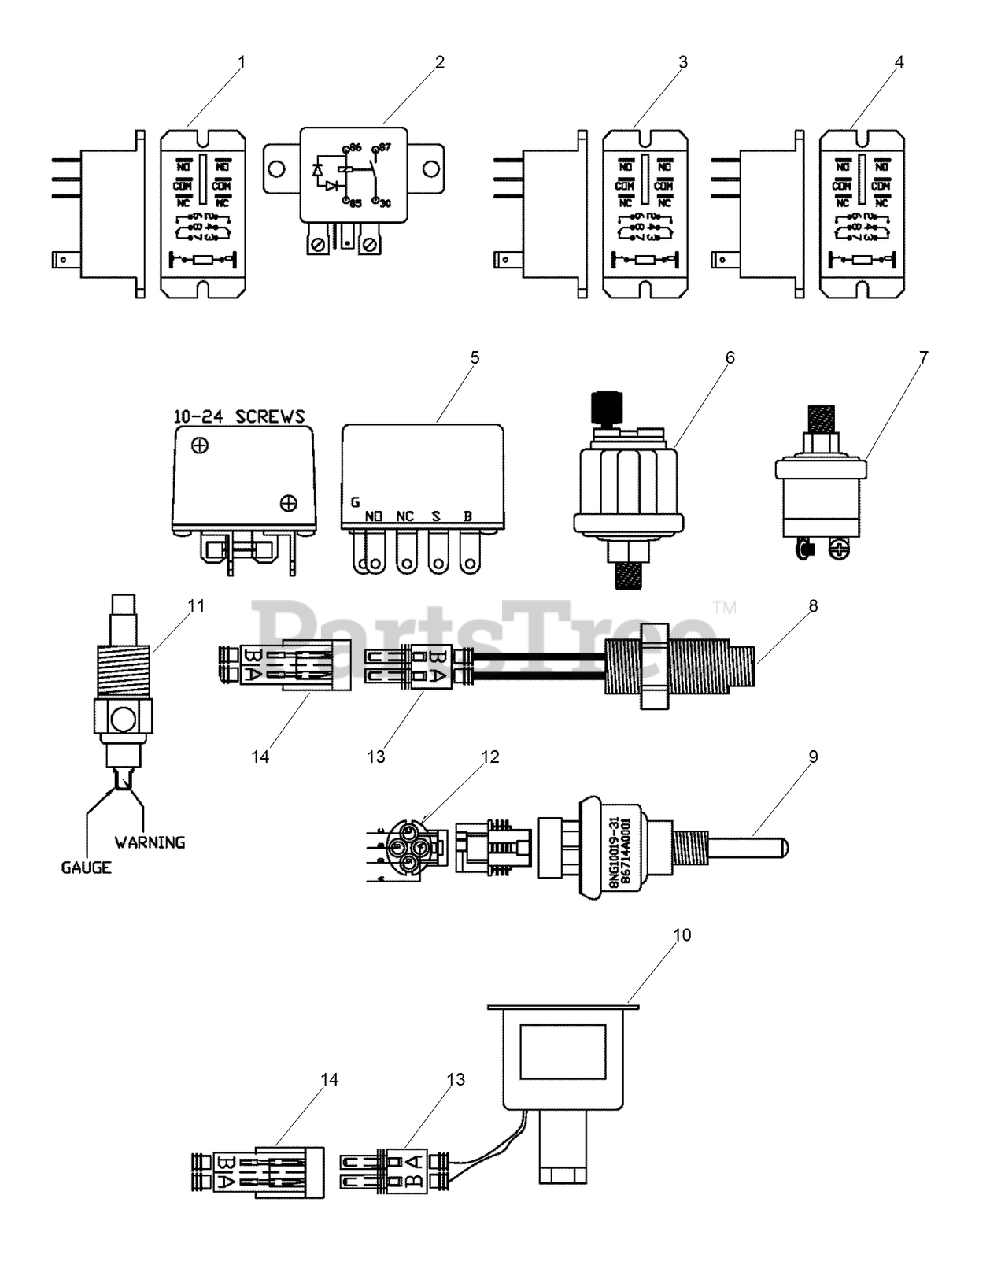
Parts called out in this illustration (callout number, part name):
1	RELAY - 2 Pole 12 VDC Panel Mount
2	RELAY - Power, 12 VDC
3	RELAY - 2 Pole 12 VDC Panel Mount
4	RELAY - 2 Pole 12 VDC Panel Mount
5	RELAY-CONTROL, ENGINE
6	SENSOR-PRESSURE, OIL
7	SENSOR-PRESSURE, OIL
8	SENSOR-COOLANT
9	CONNECTOR ASSEMBLY - 2 Pin
10	CONNECTOR ASSEMBLY - 2 Socket
11	SENSOR-RPM, MAG PICKUP
12	CONNECTOR ASSEMBLY
13	SENSOR - Coolant Level Switch
14	KIT - Cold Start
